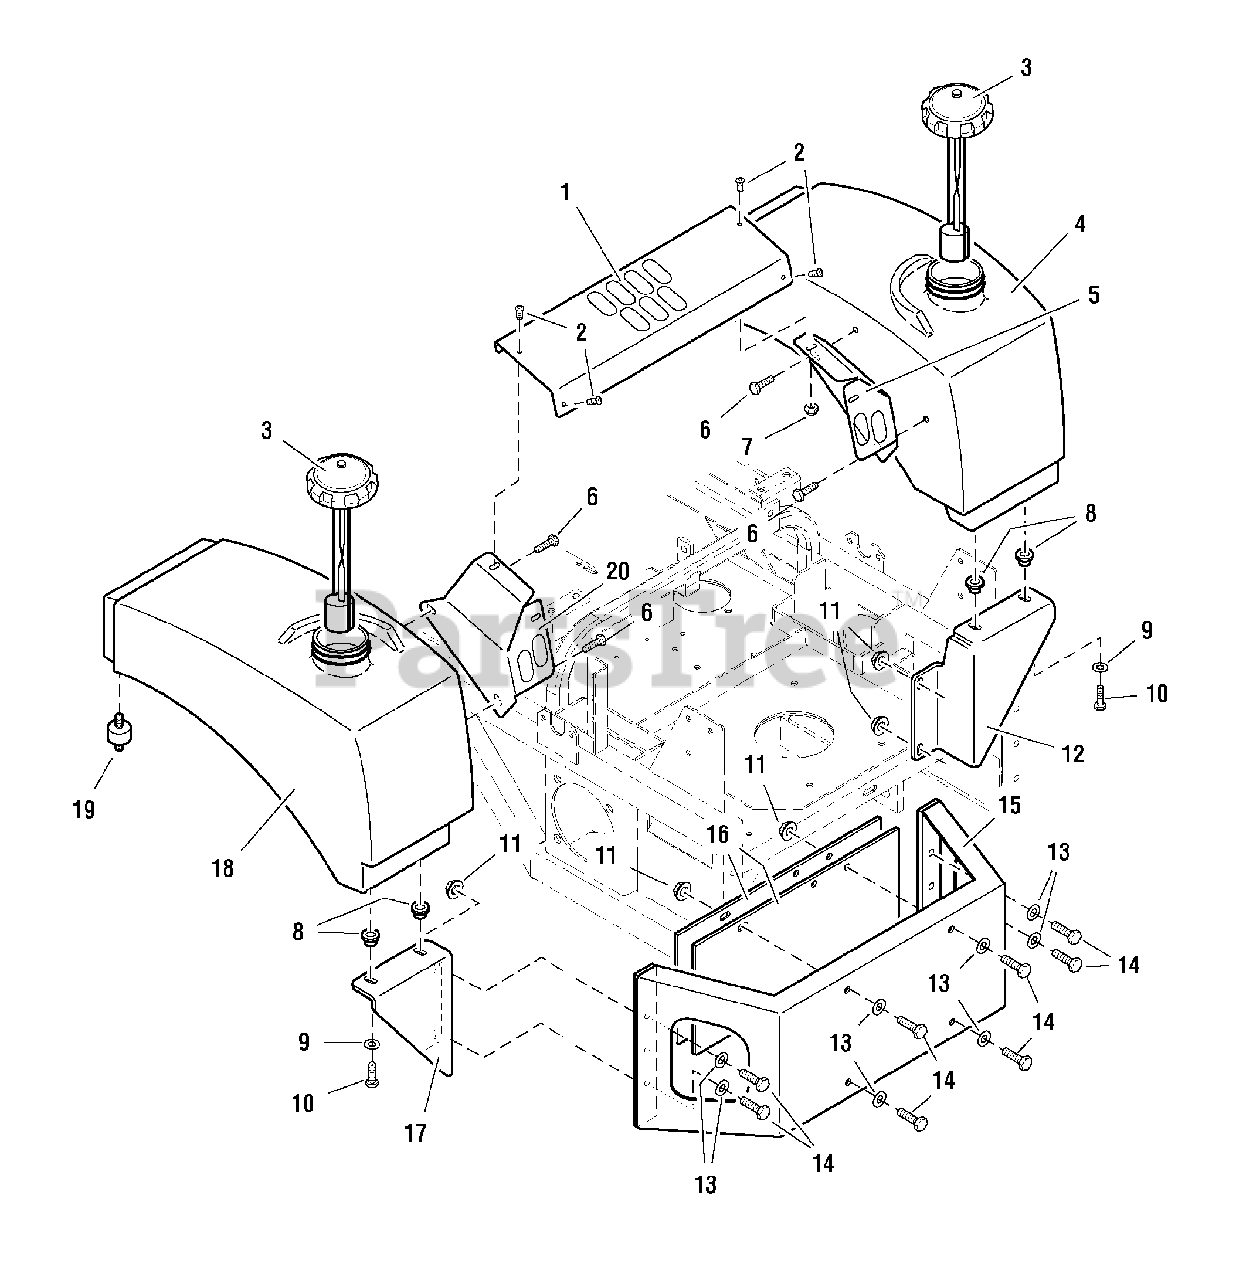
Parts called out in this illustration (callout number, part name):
1	FUEL TANK TIE BAR
2	SCREW, Allan Hd, 1/4-20 x 3/4
3	CAP, Fuel Tank w/ Gauge
4	FUEL TANK-RH, complete (see footnote)
5	TIE BAR MOUNT-RH
6	CAPSCREW, Hex Hd, 5/16-18 x 3/4
7	NUT, Hex, Nylon Lock, 1/4-20
8	RUBBER BUSHING
9	WASHER, 5/16
10	CAPSCREW, Hex Hd, 5/16-18 x 1-1/4
11	NUT, Hex, Serrated Flange, 3/8-16
12	TANK MOUNT-RH
13	WASHER, 3/8
14	CAPSCREW, Hex Hd, 3/8-16 x 1-1/4
16	COUNTERWEIGHT (52" model only)
17	TANK MOUNT-LH
18	FUEL TANK-LH, complete (see footnote)
19	RUBBER ISOLATOR
20	TIE BAR MOUNT-LH
